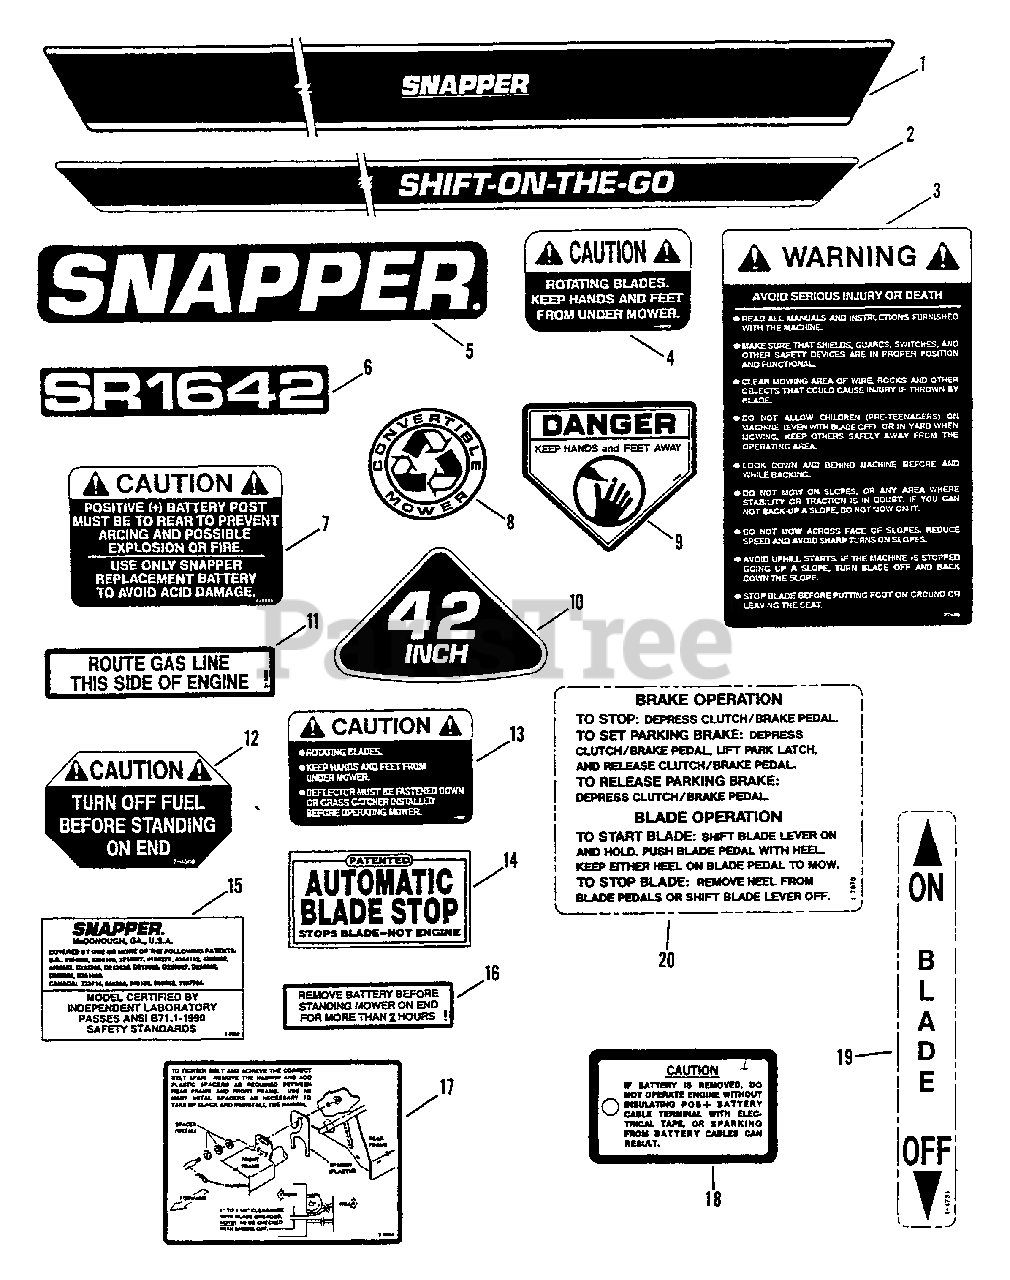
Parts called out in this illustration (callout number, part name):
1	DECAL, Banner (Blue)
2	DECAL, Bumper Stripe (Blue)
3	DECAL, Warning, Safety Instruction
4	DECAL, Caution, Rotating Blades
5	SNAPPER (Molded Logo)
6	DECAL, SR1642
7	DECAL, Caution, Battery
8	LOGO, Convertible (Blue)
9	DECAL, Danger
10	DECAL, 42 Inch
11	DECAL, Fuel Routing
12	DECAL, Fuel Shut-Off
13	DECAL, Caution
14	DECAL, Automatic Blade Stop
15	DECAL, Patent
16	DECAL, Battery Storage
17	DECAL, Belt Adjustment
18	DECAL, Caution
19	DECAL, Blade Engagement
20	DECAL, Brake Operation
